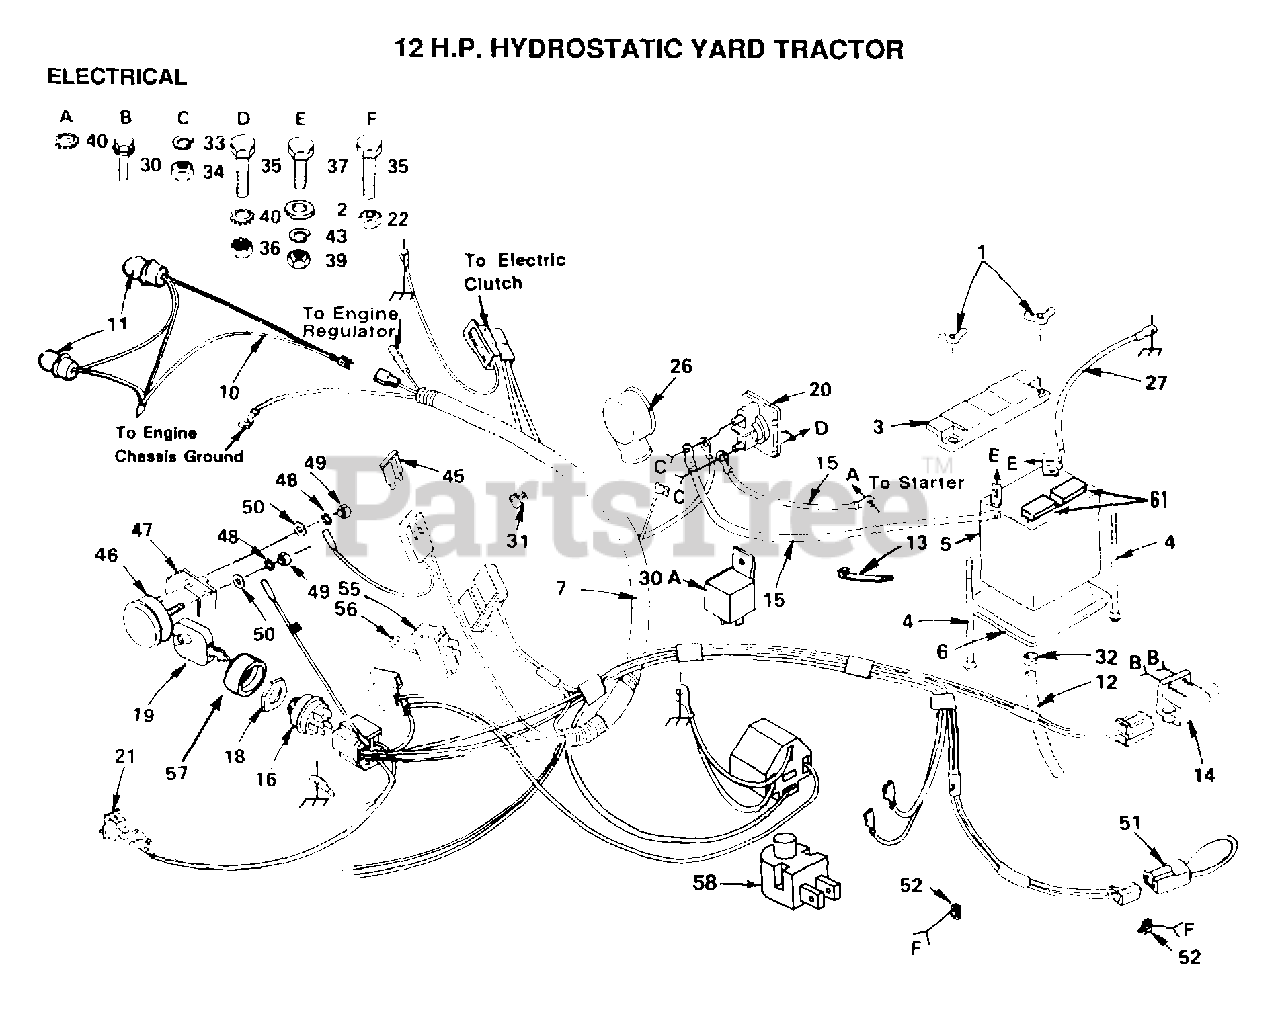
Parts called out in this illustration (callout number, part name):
2	WASHER
4	BOLT
6	"TRAY T, BATTERY"
10	HARNESS T
13	WIRE TIE
14	SWITCH-INTER. GT
15	CABLE-BATTERY T
19	KEY
21	SWITCH LT
27	CABLE T
30	SCREW
30A	RELAY ASSY T
31	CLIP T
32	HOSE CLAMP T
34	NUT
35	BOLT
36	NUT
37	BOLT LT
43	LOCKWASHER
45	FUSE HYT
46	AMMETER T
50	WASHER
52	CLIPT
55	SWITCH.PTO.T
56	HEX NUT T
58	SWITCH SEAT
61	"CAP,BATTERY "
